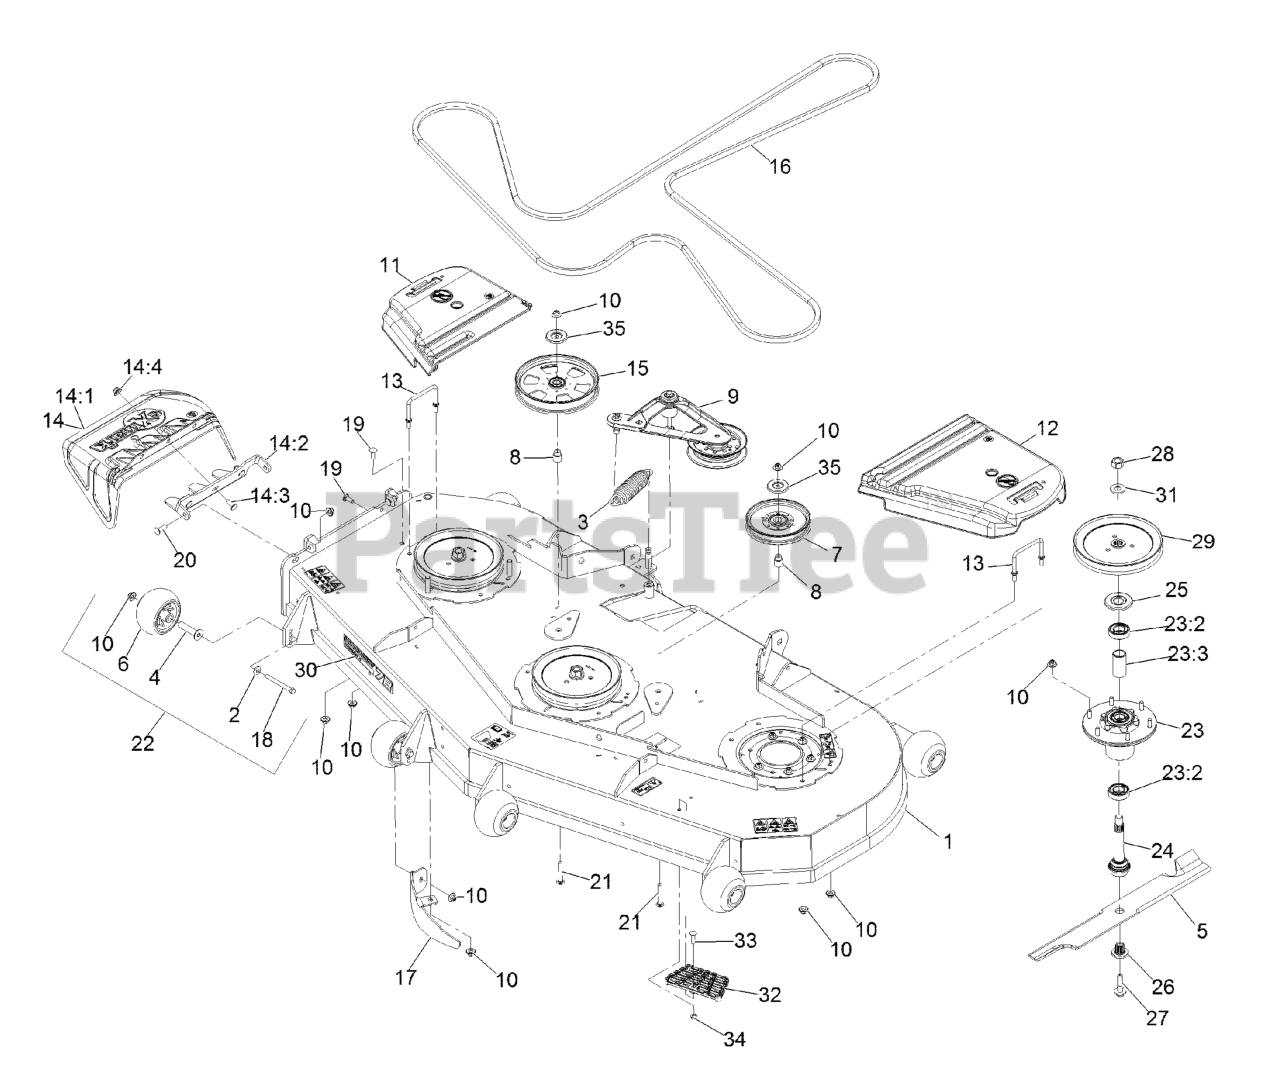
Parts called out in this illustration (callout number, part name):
1	ASM,DECK W/DECALS 724
2	WASHER-BELLEVILLE
3	SPRING-EXTENSION
4	AXLE, ROLLER
6	ROLLER-SCALP, ANTI
7	IDLER-PULLEY
8	BUSHING-IDLER
9	DECK IDLER ASM
10	Nut-Nyloc 3/8-16 Flg
11	COVER-BELT, RH
12	COVER-BELT, LH
13	WIREFORM-COVER
14	ASM,DISCHARGE CHUTE
14:1	CHUTE,DISCHARGE
14:2	BRACKET,DISCHARGE CHUTE
14:3	SCREW-CARR
14:4	Nut-Nyloc 3/8-16 Flg
15	PULLEY-IDLER, FLAT
16	BELT-V
17	BAFFLE-DOGLEG, LZ72
18	SCREW-HH 3/8-16 X 3 3/4 GR 8
19	SCREW-CARR
20	Bolt-Carriage 3/8-16 X 1 1/4
21	SCREW-CARR
22	KIT, ANTI-SCALP ROLLER
23	ASM-CUTTER HSG WITH BEARINGS
23:2	BEARING-BALL
23:3	SPACER-BEARING
24	ASM-SPINDLE AND SEAL
25	GUARD,BEARING TOP .989
26	BUSHING,SPLINED
27	SCREW,SEMS 1/2-20 X 2.19
28	NUT-HEX
29	SHEAVE,BLADE DRIVE 8.74
30	DECAL, 724
32	STEP-DECK
33	Bolt-Carriage 5/16-18 X 1 1/4
34	NUT-HF, NI
35	SHIELD-DUST
